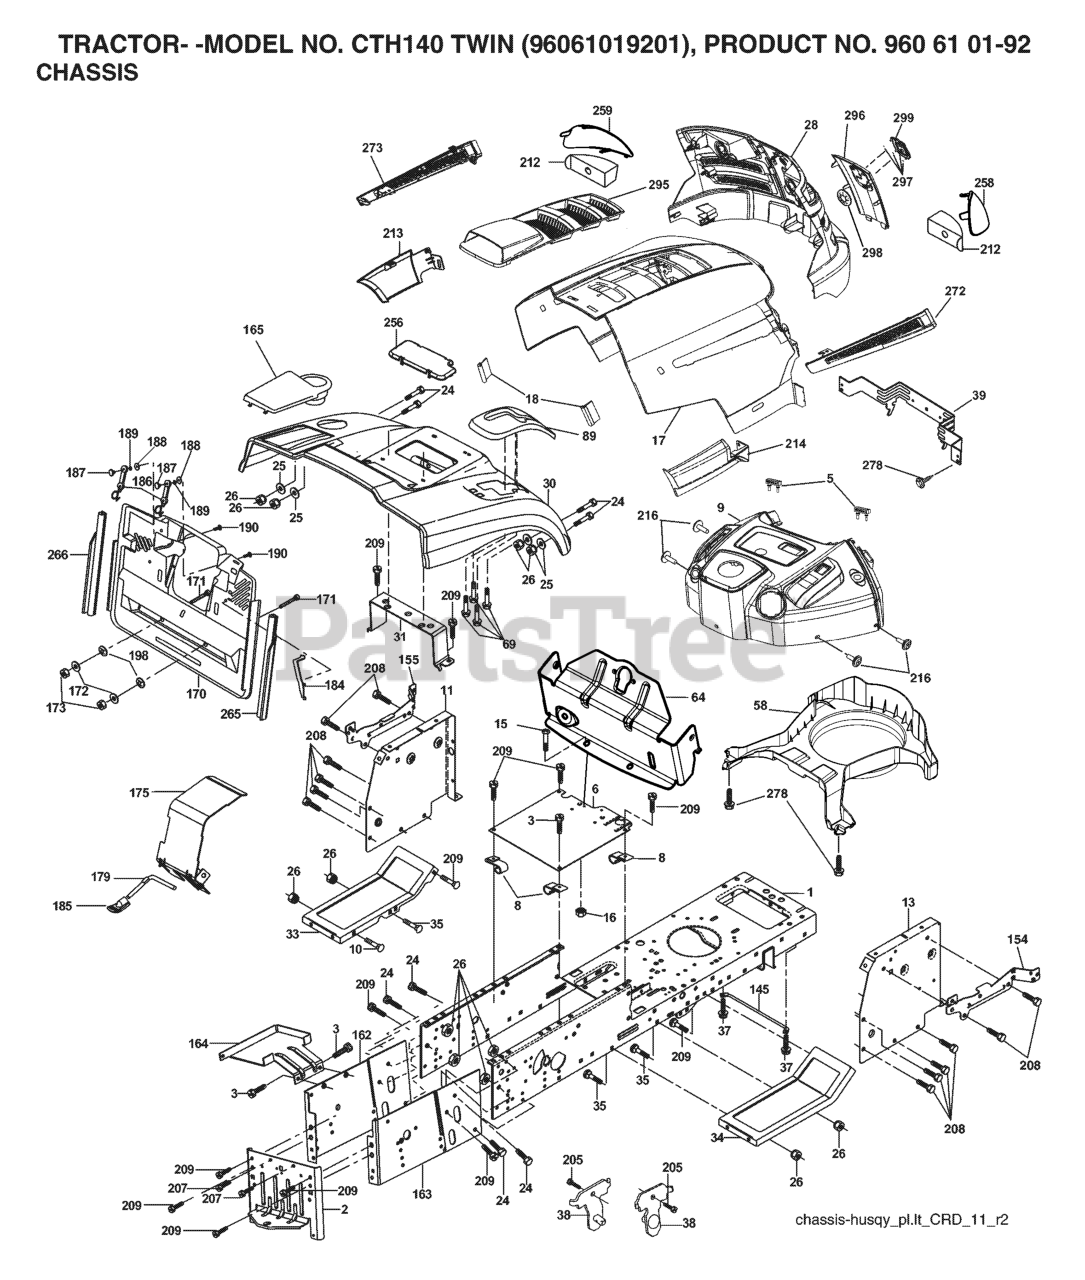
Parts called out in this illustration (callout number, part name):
2	DRAWBAR
3	SCREW 3/8-16X3/4
5	BUMPER DASH
6	PLATE
8	CLIP,INSULATOR
10	BOLT D
11	PANEL.DASH.LH.LTX
13	PANEL ASM, DASH RH
15	Screw, Machine, Truss Head 5/16-18 UNC x 3/4
16	NUT
17	HOOD
18	BUMPER.HOOD.TEX.HUSQVARNA
25	WASHER
26	NUT
28	RP GRILLE/LENS ASM.
30	CONSOLE.CRD.AUTO.GRY
31	BRACKET SUPPORT FENDER
33	FOOTREST PNT LH
34	FOOTREST PNT RH
37	Screw 5/16-18 x 1/2 Hex, Self Tapping 5/16-18 x 1/2
38	BRACKET ASM PIVOT MOWER REAR
39	BRACKET PIVOT
69	SCREW.HI-LO.CONSOLE
89	CONSOLE.CRD.AUTO.GREY.2005
145	ROD.PIVOT.HOOD
162	BRACKET
163	BRACKET EXTEN CHASSIS RH CRD
165	RP.COVER.BATTERY.CRD.GREY
172	WASHER
175	DOOR TRAP
179	ROD PIVOT FBI
184	BRACKET.ACTUATOR.BAGGER.SRD
186	LATCH ASSY
187	WELDNUT
189	LOCKWASHER #10
190	SCREW
207	SCREW, 5/16-18 X 1/2
208	SCREW 3/8-16X1/2
209	SCREW, 3/8-16X3/4
212	INSERT REFLECTIVE
213	SKIRT SIDE LH
214	SKIRT SIDE RH
216	SCREW HEXWSHR 1/4-20X3/4
256	COVER FENDER CRD
258	LENS.HUSQVARNA LT.RH
259	LENS.HUSQVARNA LT.LH
265	SEALING
266	SEALING
272	VENT SIDE HOOD RH
273	VENT SIDE HOOD LH
278	SCREW
295	VENT TOP HOOD
296	TRIM
297	CLIP.RETAINER.TINNER.
298	NUT PUSH M
299	RP LOGO
